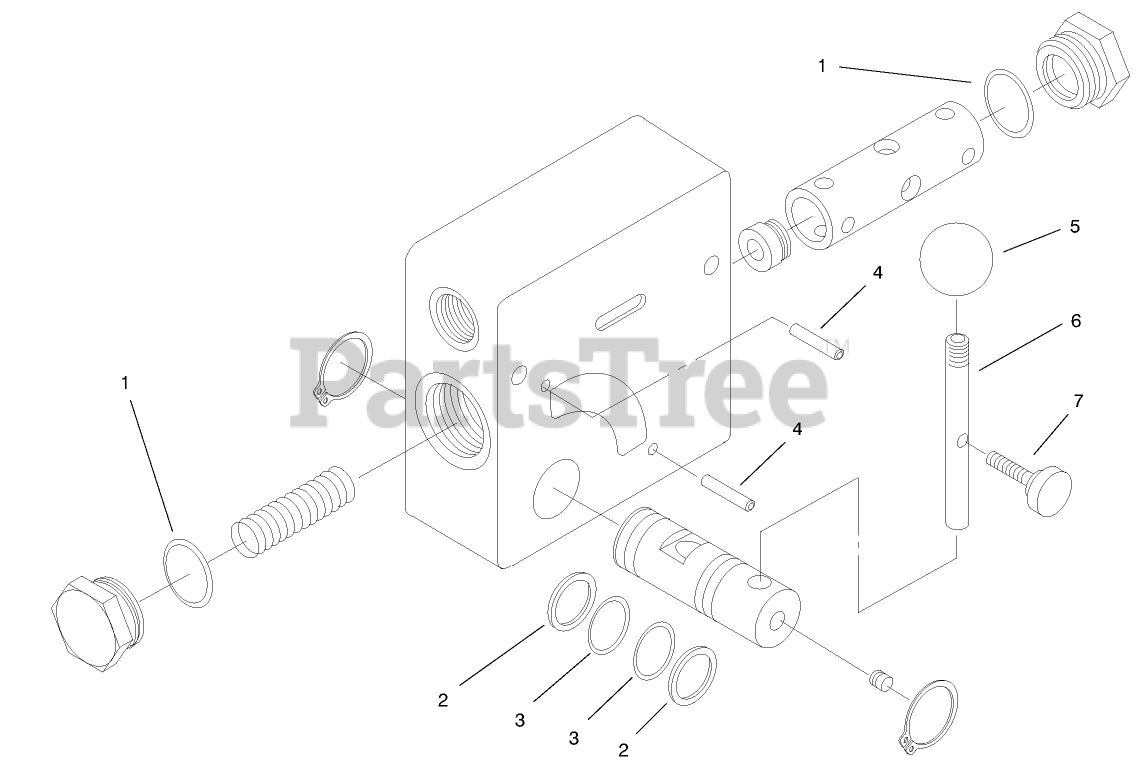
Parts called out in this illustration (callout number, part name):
2	Back-Up Washer
4	Roll Pin
5	Handle Knob
6	Handle
7	Thumb Screw
